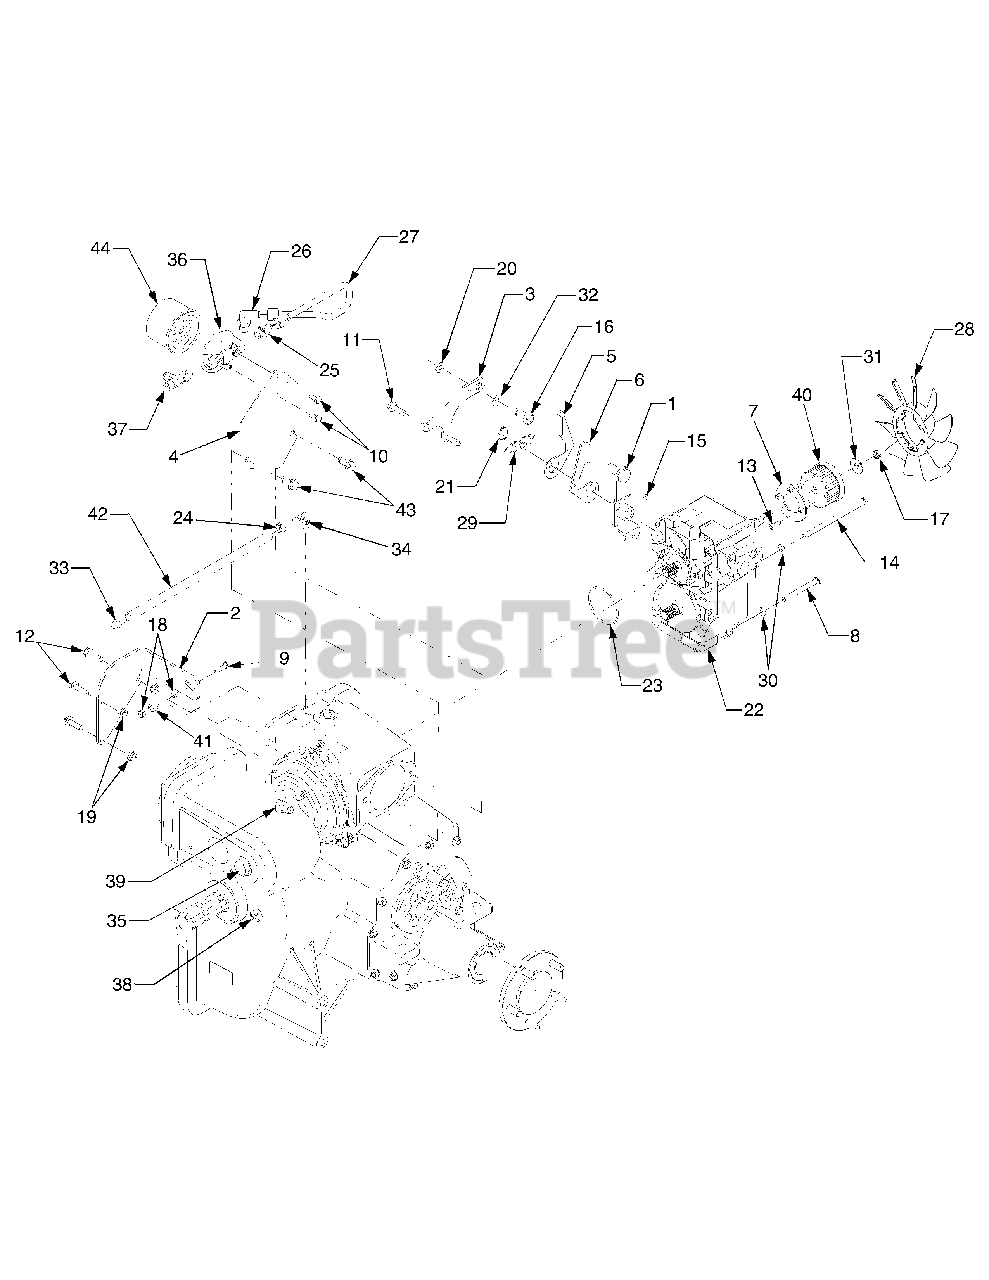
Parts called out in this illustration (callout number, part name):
1	Arm, Hydro
2	Bracket, Clutch Torque
3	Bracket, Return
4	Bracket, Filter Mounting
5	Arm, Neutral - RH
6	Arm, Neutral - LH
7	Keeper, Belt
8	Screw, Hex Cap, 5/16-18 x 3.0 GR5
9	Screw, Hex Cap, 1/4-28 x 1.0 GR5
10	Screw, Hex Cap, 1/4-20 x .62 GR5
11	Screw, Hex Wash. Hd. Tapp, 5/16-18 x 1.25 GR5
12	Screw, Hex Flange, 5/16-18 x 1.5 GR5
13	Screw, Socket Hd. Cap 1/4-20 x .62 GR8
14	Screw, Hex Cap Lock, 5/16-18 x 5.5 GR5
15	Screw, Set - Lock 5/16 x .5 GR5
16	Screw, Shoulder, .497 x .750: 3/8-16
17	Nut, Hex Jam Lock, 3/8-24
18	Nut, Hex Nylon Lock, 1/4-28
19	Nut, Hex Flange Lock, 5/16-18 GR5
20	Nut, Hex Flange Lock, 3/8-16
21	Ring, Retaining
22	Pump, Hydrostatic Transmission
23	O-Ring, 2.425 ID x .103
24	Clamp, Hose
25	Fitting, Straight
26	Fitting, 90 Degree
27	Tube, Hydro Inlet
28	Fan, Transmission Cooling
29	Spring, Extension, .50 x 1.975 x.072
30	Washer, Lock, 5/16
31	Washer, Belleville
32	Washer, Thrust, .375 x .812 x .06
33	Vent, 3/8 Dia
34	Fitting, Elbow
35	Fitting, Plug
36	Adapter, Oil Filter
37	Fitting, Run Tee
38	Indicator, Oil Level Sight
39	Fitting, Elbow
40	Adapter. Cog Pump
41	Hose, Fuel Line .38in
42	Hose, Vent 13 in.
43	Screw, Hex Wash Hd Tapp 3/8-16 x .62
44	Filter, Hydro Pump
